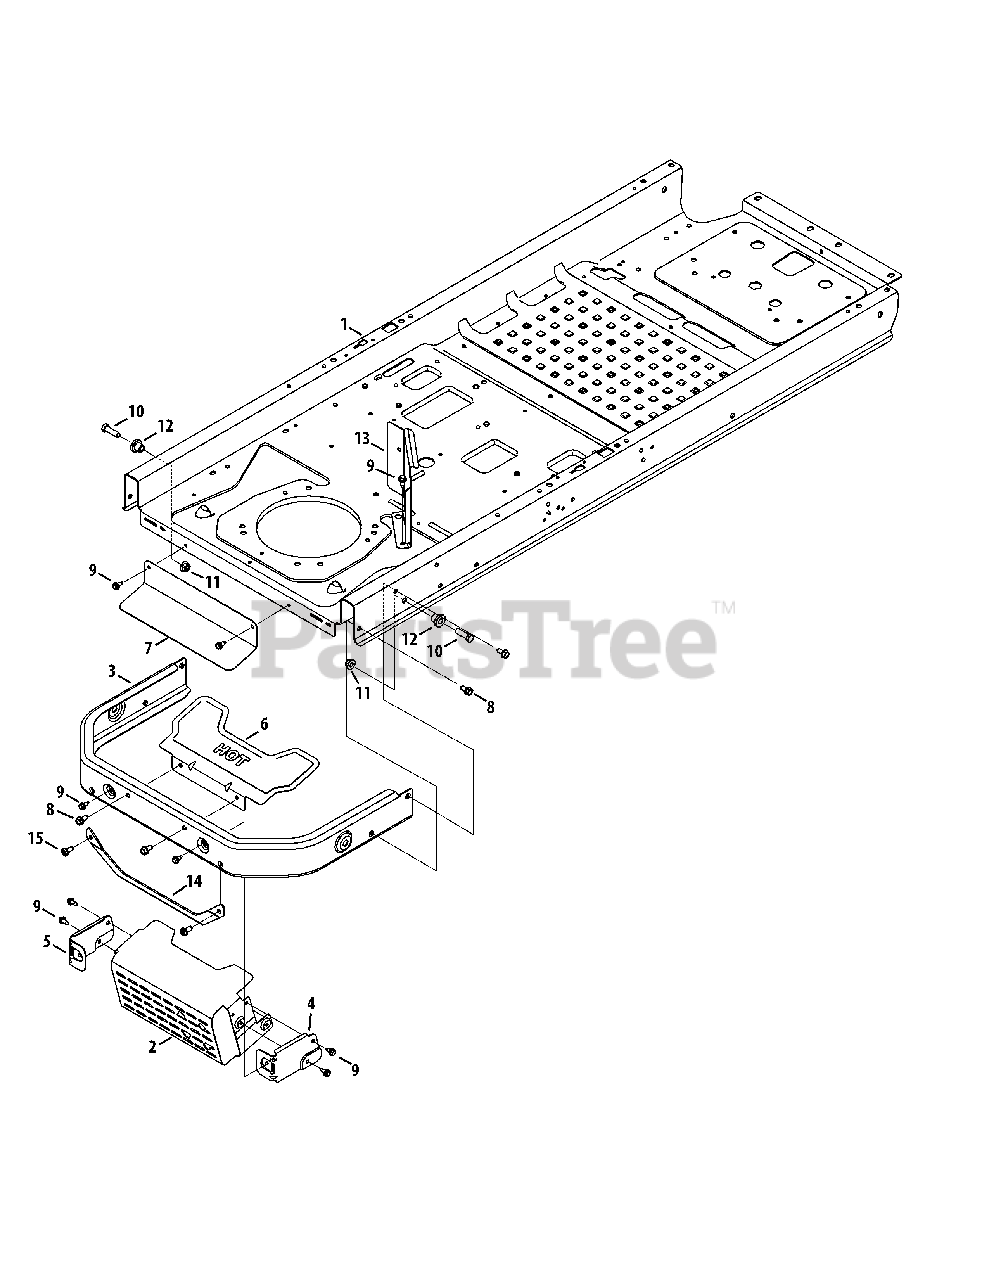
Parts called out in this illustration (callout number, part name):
1	Frame Assembly
2	Muffler Shield Assembly
3	Rear Bumper
4	Muffler Mounting Shield Bracket, RH
5	Muffler Mounting Shield Bracket, LH
6	Muffler Shield
7	Lower Heat Shield
8	Hex Washer Screw, 5/16-18 x .750
9	Hex Washer Screw, 1/4-20 x .625
10	Hex Screw, 3/8-16 x 1.25
11	Flange Lock Nut, 3/8-16
12	Shoulder Spacer, .38 x 1.0 x .70
13	Engine Heat Shield
14	Rear Muffler Shield Bracket
15	Screw, Self-Tapping, 5/16-18, 0.750
